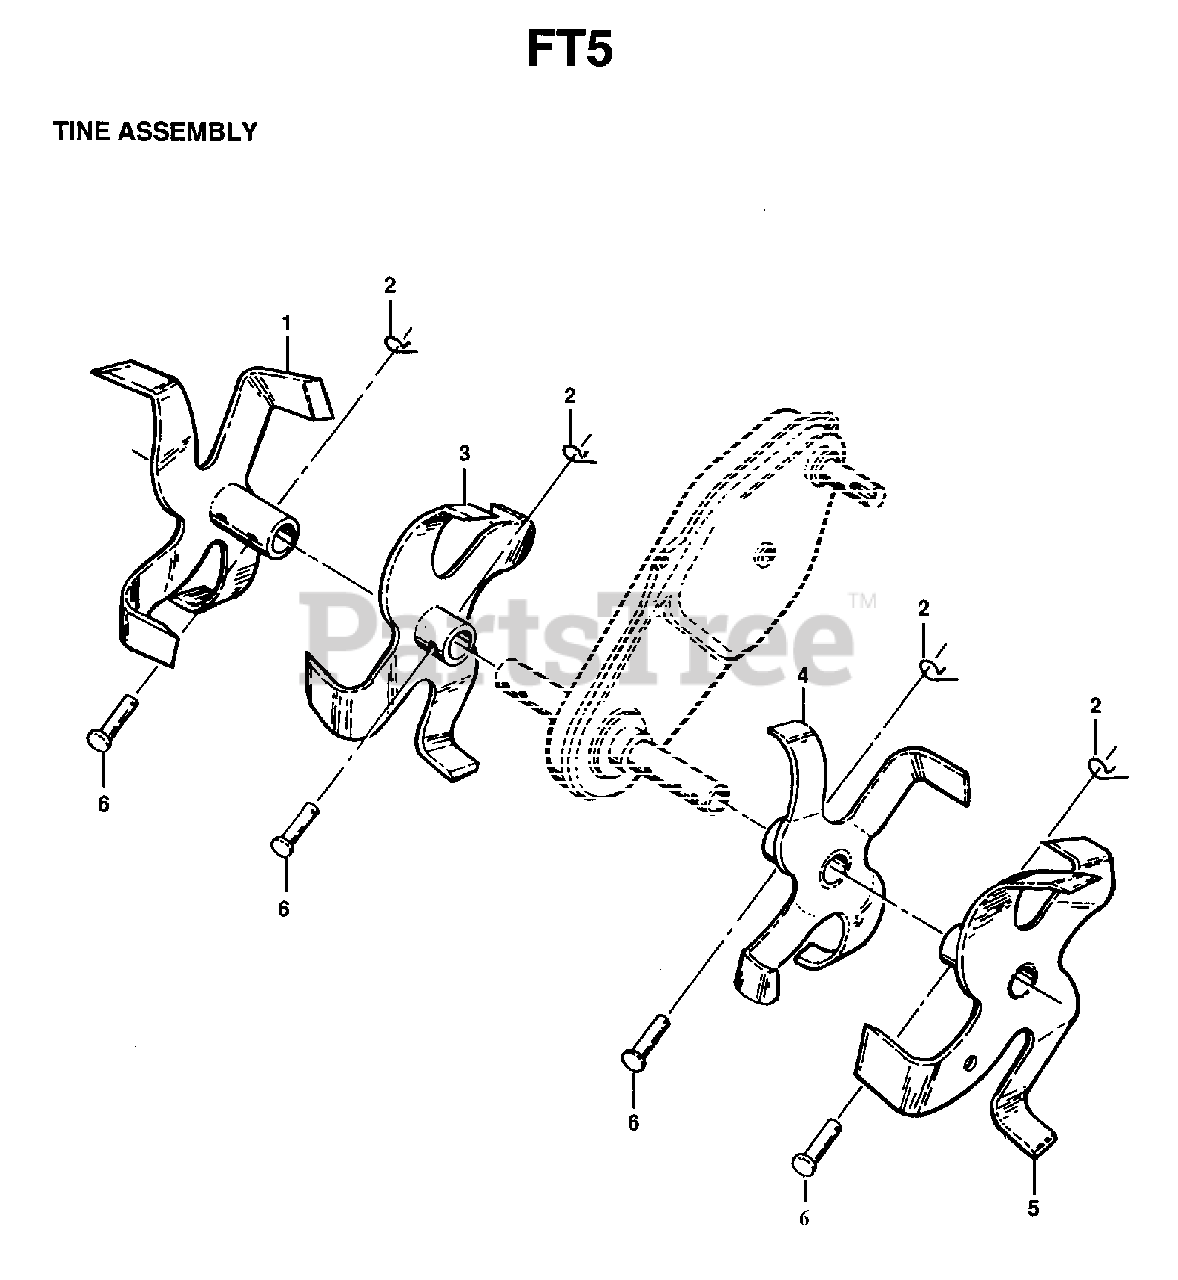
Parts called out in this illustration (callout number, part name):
1	TINE.LH.12"
2	CLEVIS PIN
3	TINE.LH.12"
4	SPRING RETAINER
5	HUB & PLATE ASM LH
6	NUT
7	WASHER, LOCK 3/8
8	BOLT.HEX.001X20.37-24X1.ZINC
9	TINE.RH.12"(72R)
10	HUB & PLATE ASM RH
11	TINE.RH.12"(72R)
